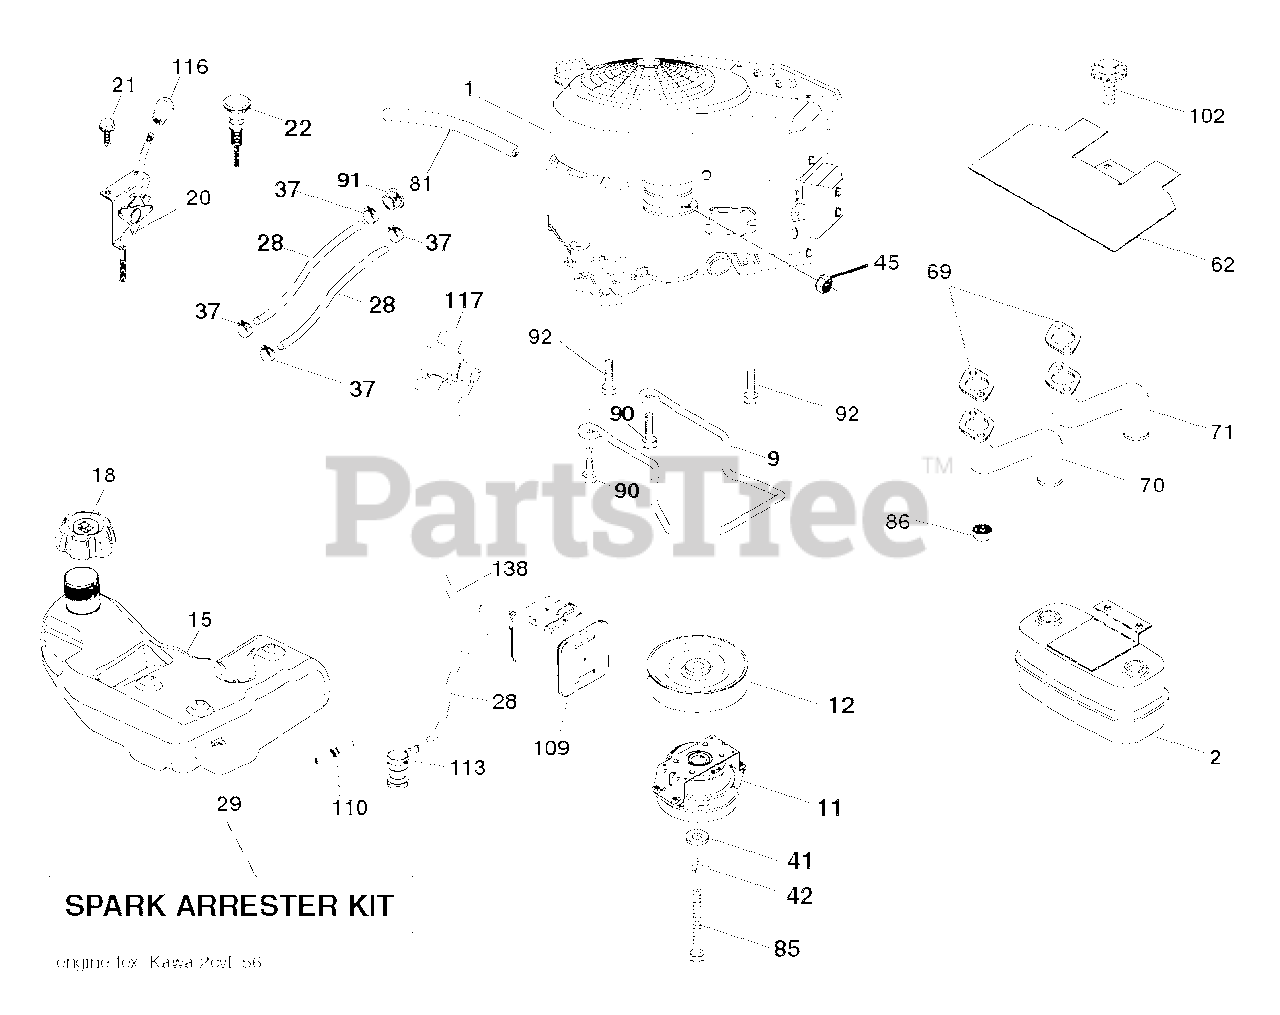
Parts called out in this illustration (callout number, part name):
2	MUFFLER.ASM.TWN.EXTNDED.DFLCTR
9	KEEPER.BELT.ENG.4.25"2.BLT.431
11	CLUTCH. 5.0 PD. 2.5 OFFSET
12	PULLEY.EXTENDED.SHAFT.GROUND
15	TANK.ASM.4.GAL.CARB.1.PORT.REA
18	CAP ASSY FUEL 3" GRAY
20	CONTROL.THROTTLE.PRO.
21	SCREW.#10 X 0.750.BOS
22	CONTROL, CHOKE
28	LINE.FUEL.64"REAR.EMIS
29	KIT.SPARK ARRESTOR 794945 B&S
37	HOSE CLAMP
42	LOCKWASHER
45	NUT
62	SHIELD.HEAT.MUFFLER
70	TUBE.EXHAUST.LH.FR961/FR730
71	TUBE.EXHAUST.RH.FR961/FR730
81	TUBE, DRAIN OIL ASM.
85	BOLT.HEX.7/16-20X5.GR5.GREEN
86	NUT.HEX.FLANGE.TOPLOCK
90	SCREW 3/8-16X1
91	BUSHING.1.375OD
92	SCREW 3/8-16X1
102	SCREW
109	CANNISTER, CARBON
110	VALVE.ASM.ANTI-SLOSH
111	RP PURGE LINE
113	VALVE.SLANT.CARTRDG.90 DEG.TEX
116	KNOB - SHIFT
117	VALVE FUEL RESERVE
138	PURGE.LINE.36"REAR.CALIFORNIA
